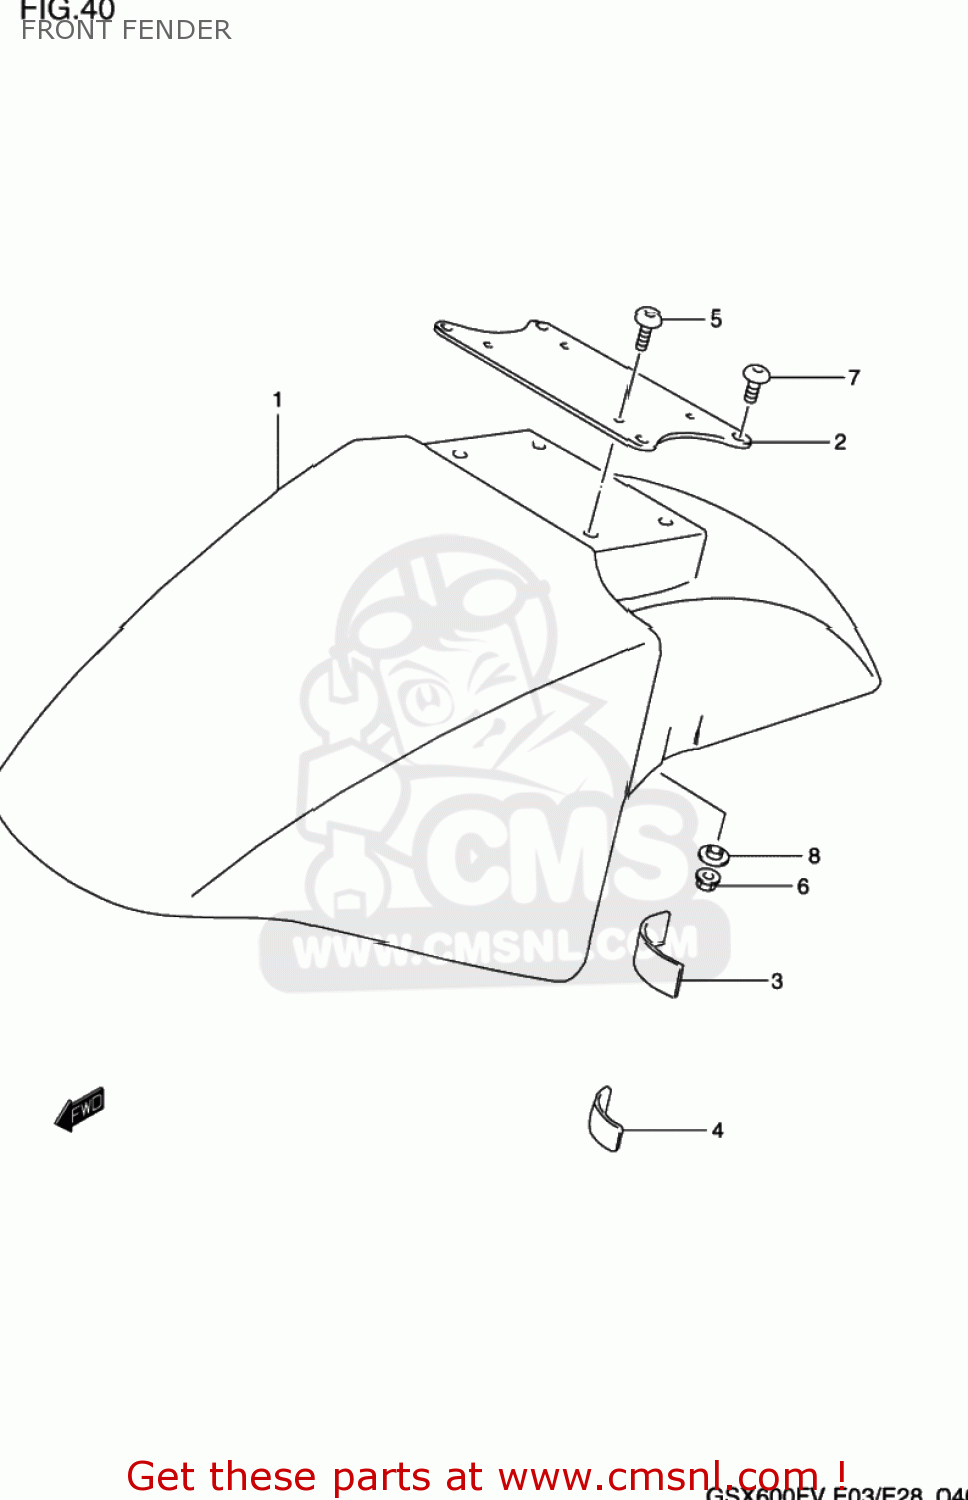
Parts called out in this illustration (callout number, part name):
1	FENDER,FR
2	BRACE,FR FENDER
3	CUSHION,FRONT FENDER
4	CUSHION
5	SCREW
6	NUT
7	SCREW(6X12)
8	WASHER
